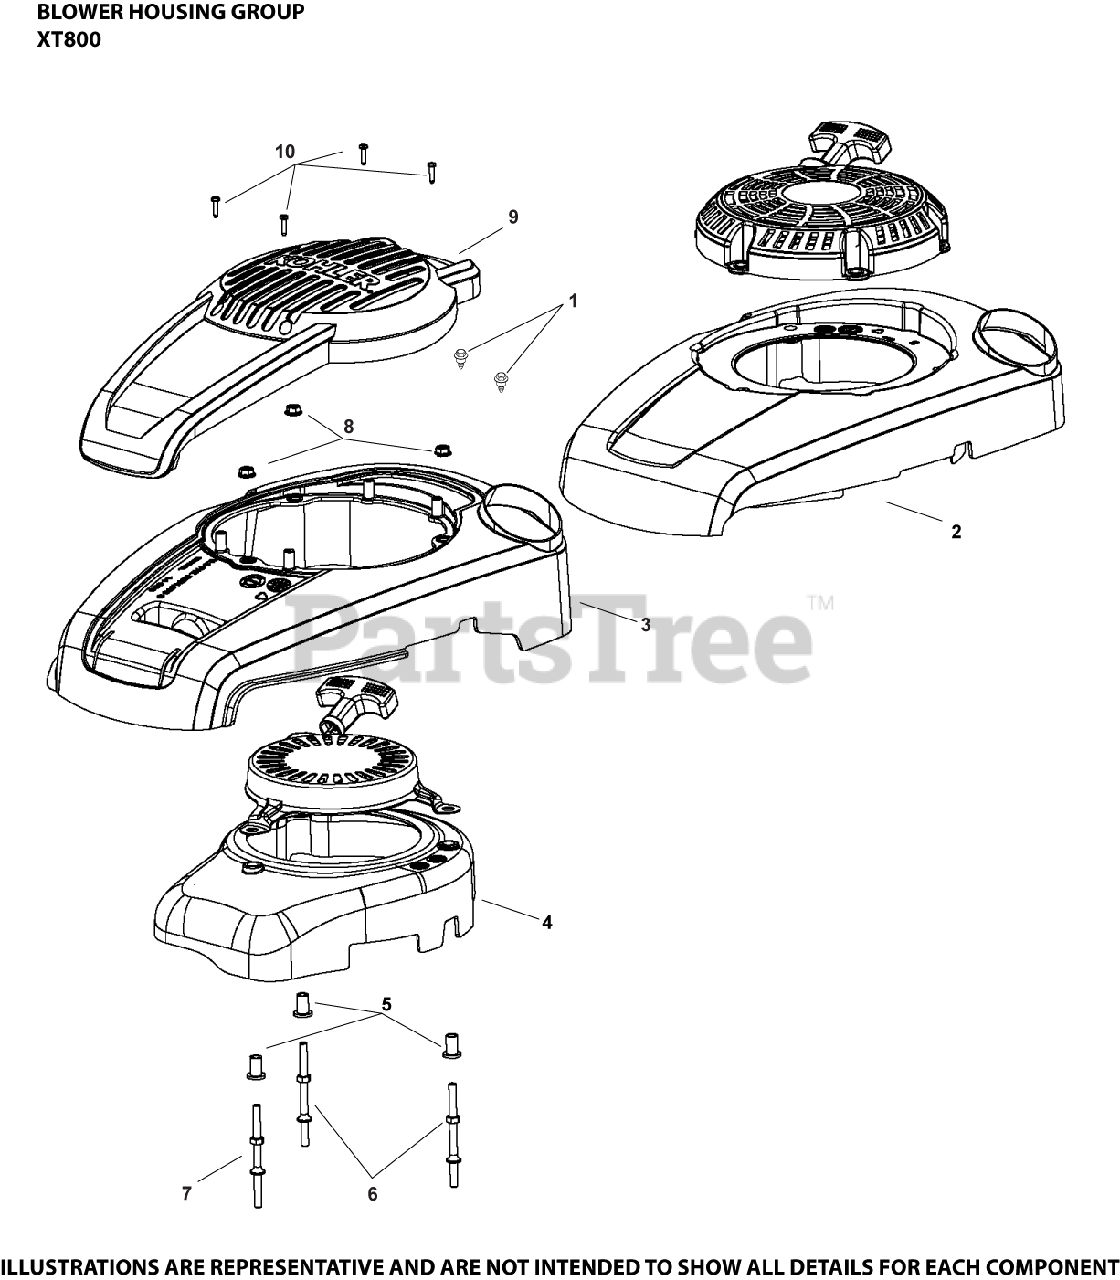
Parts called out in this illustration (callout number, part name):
1	SCREW, SHOULDER (M5) USE 25 086 288-S
2	COVER, ENGINE
6	STUD - (#1407226S)
7	STUD - (#1407225S)
8	NUT, HEX FLANGE (M6) - USE 14 100 16-S
